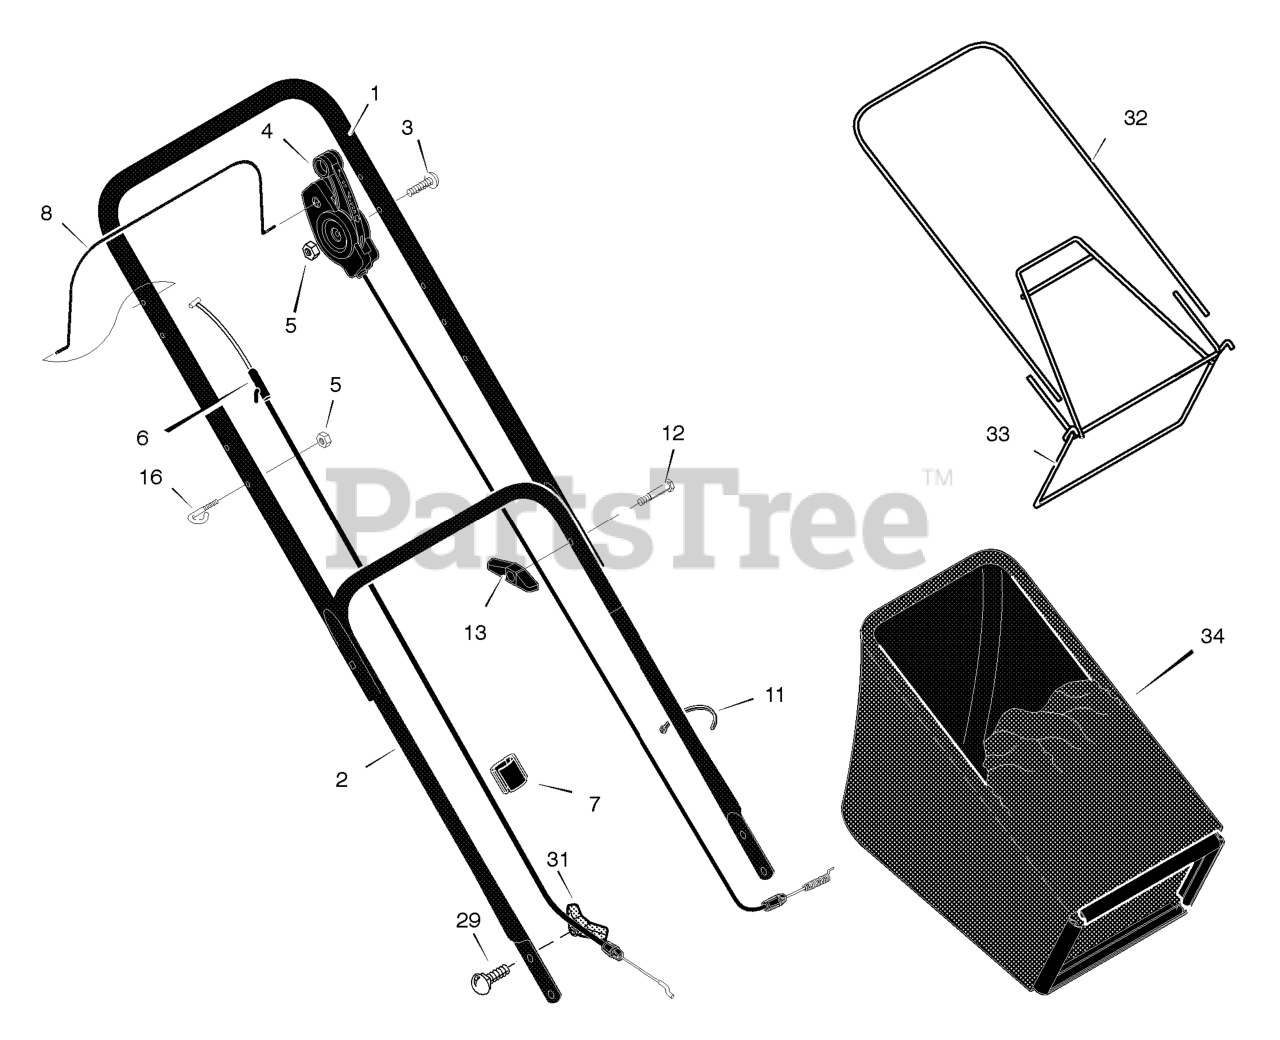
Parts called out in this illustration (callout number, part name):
1	Handle, Upper
2	Handle, Lower
4	Control, Drive
5	Locknut
6	Cable, Stop
7	Fastener, Cable
8	Lever, Stop
11	Fastener, Cable
13	Knob
16	Guide, Rope
29	Bolt, Carriage
31	Knob, Plastic
32	Tube, Bag
33	Frame Assembly
34	Bag, Cloth
